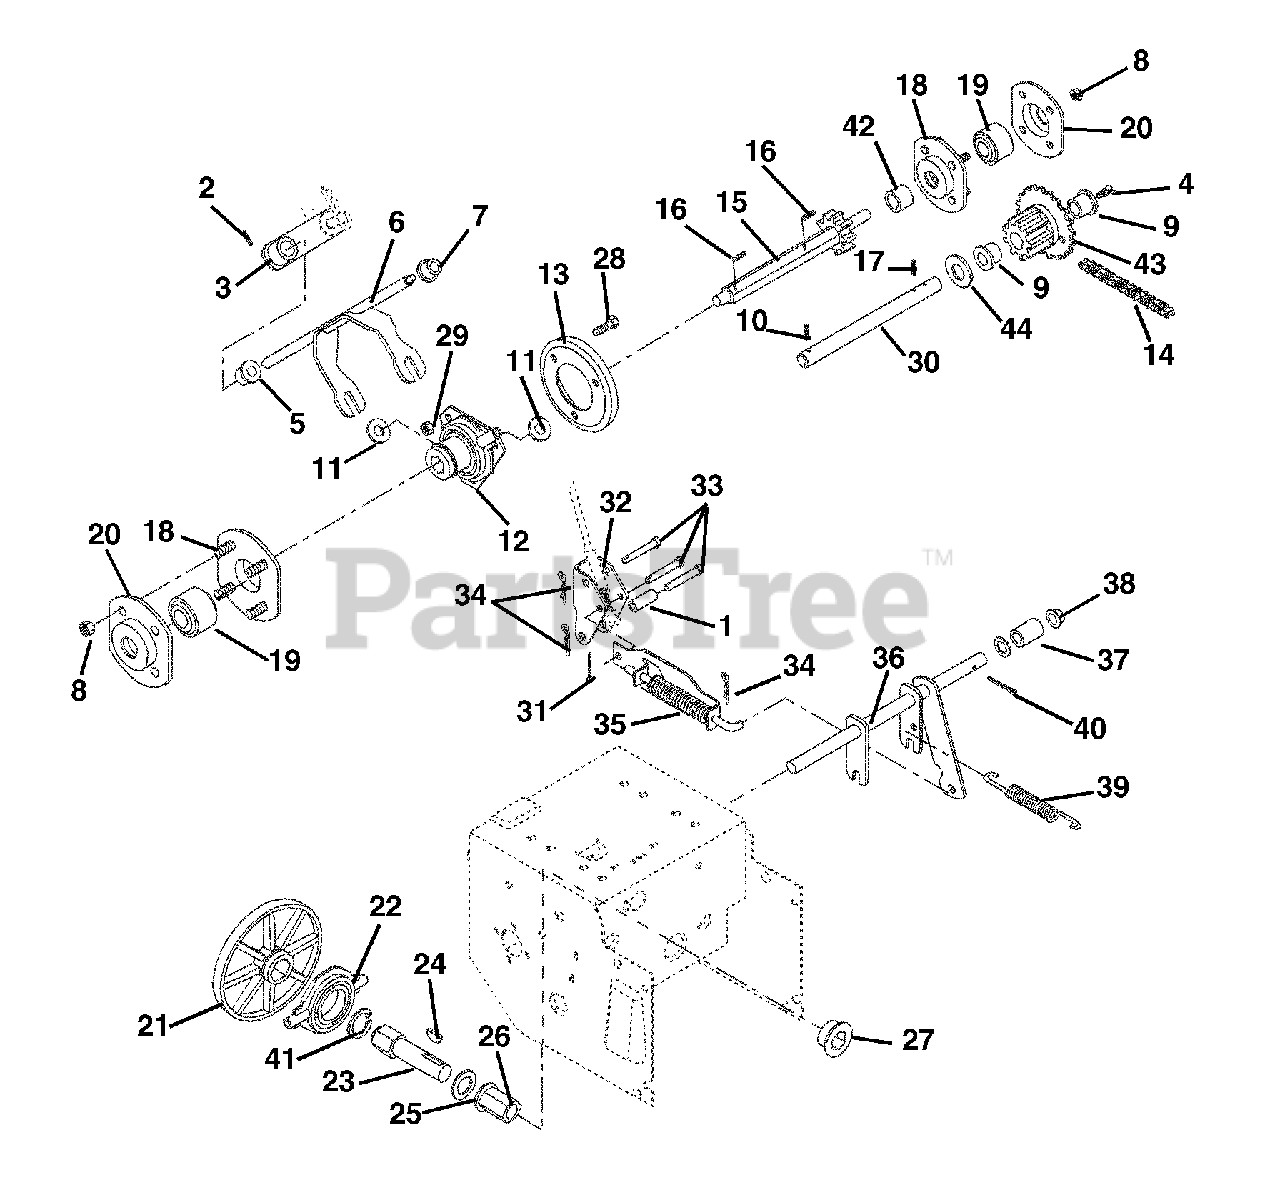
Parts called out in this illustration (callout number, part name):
1	SPACER .322X.626X.50
2	PIN-ROLL .156X.88
3	WMT, SPEED CHANGE ARM
4	DRIVE FITTING, HYD. BRIGHT ZC
5	BSHG-FLG.500X.625X.312X.750NY
6	FORK-SPEED
7	BSHG-FLG .325X.444X.440X.560
8	NUT-LK-DUAL FACE 10-24 YWZC
9	BSHG-FLG .625X.750X.500X.875BR
10	PIN-ROLL .156X1.00
11	WSHR-FL-STL .505X1.00X.062YWZC
12	SHIFT CARRIER
13	DISC, FRICTION - 730 MAT'L
14	CHAIN, ROLLER #41 X 27 P
15	WMT, HEX SHAFT
16	PIN-ROLL .125X.88
17	PIN-ROLL .125X1.00
18	BEARING FLANGE
19	BRG-BALL .437X1.375X.437
20	BEARING FLANGE
21	FRICTION PLATE
22	BEARING ASSEMBLY
23	HEX SHAFT
24	KEY-WDRF .188X.75X.313 SAE 9
25	WSHR, THRUST .625X1.125X.063
26	BSHG-FLG .625X.875X1.750X1.188
27	BSHG-FLG .875X1.25X.75X1.50HX
28	@BLT-HEX .25-20X.50 GR5 YWZC
29	@NUT-LK-CTR .25-20 YWZC
30	SHAFT-PINION
31	@PIN-CTR .07X.50 EXTPRSQCT YZC
32	BRACKET, TRACTION ARM
33	PIN,CLEVIS .243/.248 X 1.38 YZ
34	PIN-HAIR INT .08X.18X1.18 YWZC
35	TRACTION CLUTCH ASSEMBLY
36	CLUTCH FORK
37	SPACER .504X.748X.321
38	CAP, .50 ROD YWZC
39	SG-TENS .063X.44X1.56
40	@PIN-CTR .12X1.00 EXTPRSQCT YZ
41	RG-RTNG-EXT 1.250X.050
42	SPACER,.45 X .62 X 1.23
43	ASSY,PINION & SPROCKET
44	WSHR-FL-STL .630X1.005X.062 YZ
